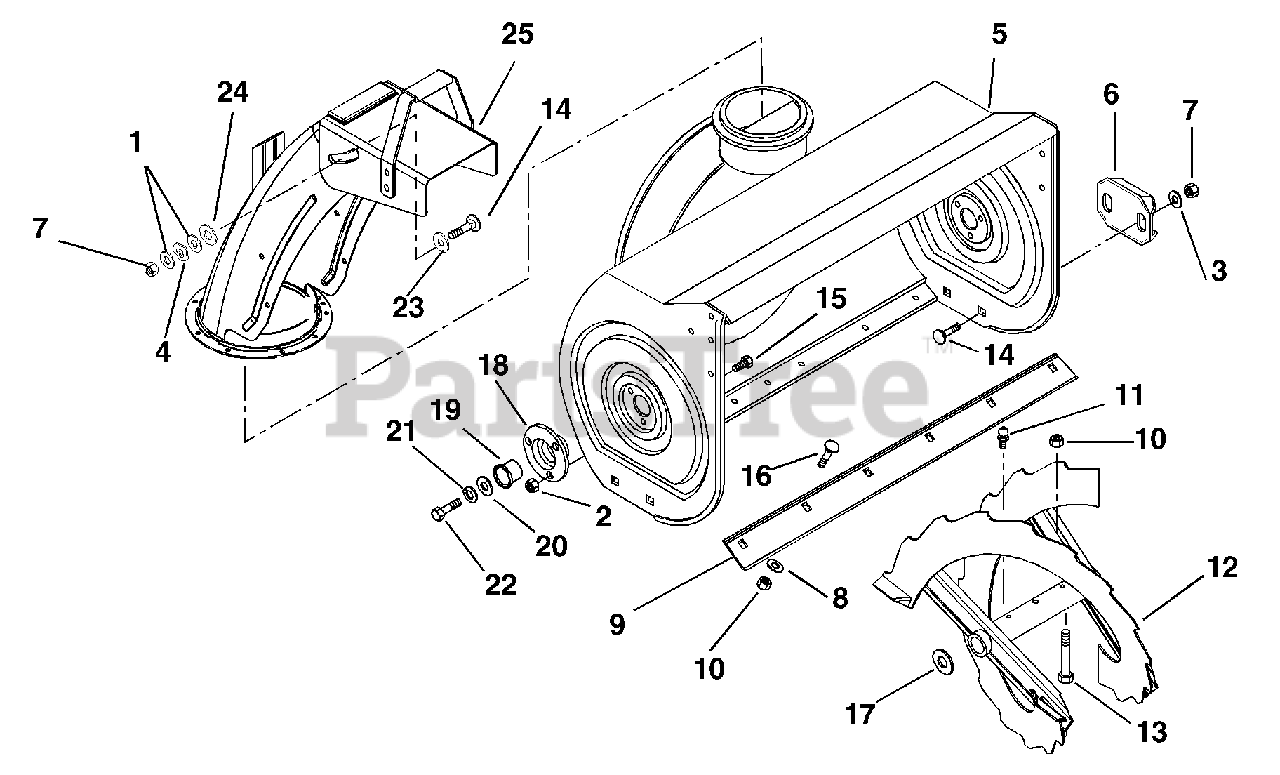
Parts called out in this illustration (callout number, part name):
1	@WSHR-FL-STL.406X.812X.065 YWZ
2	@NUT-SPNLK-FLG .25-20 YWZC
3	@WSHR-FL-STL.438X1.00X.083 YWZ
4	WAVE WASHER .390X.655X.110
5	HOUSING, 24" BLOWER W/DECAL
6	SKID SHOE, REVERSIBLE - ORANGE
7	@NUT-LK-CTR .38-16 YWZC
8	@WSHR-FL-STL.38X.875X.083 YWZC
9	SCRAPER, BLADE 24"
10	@NUT-LK-CTR .31-18 YWZC
11	FTG-LUBE .25-28X.256 YWZC
12	RAKE, RIGHT-24"(1ID X 14.75OD)
13	SHEAR BOLT SERVICE ASSEMBLY
14	BLT-RHHDSQSHNK .38-16X.75 G2YZ
15	BLT-SERNK SL .25-20X.50 YWZC
16	@BLT-RHDSSQNK .31-18X.62 G5YZ
17	WSHR-FL-STL 1.010X1.505X.062YZ
18	BEARING SUPPORT
19	BSHG-FLG 1.000X1.12X.62X1.50BR
20	WSHR-FL-STL.511X1.441X.125 YWZ
21	WSHR-LK .500X.151 HVY YWZC
22	@BLT-HEX .50-13X1.00 GR5 YWZC
23	WSHR-FL-STL .52X.827X.062 YWZC
24	WSHR-PLASTIC .390X.875X.062
25	CHUTE, DISCHARGE W/O REMOTE
